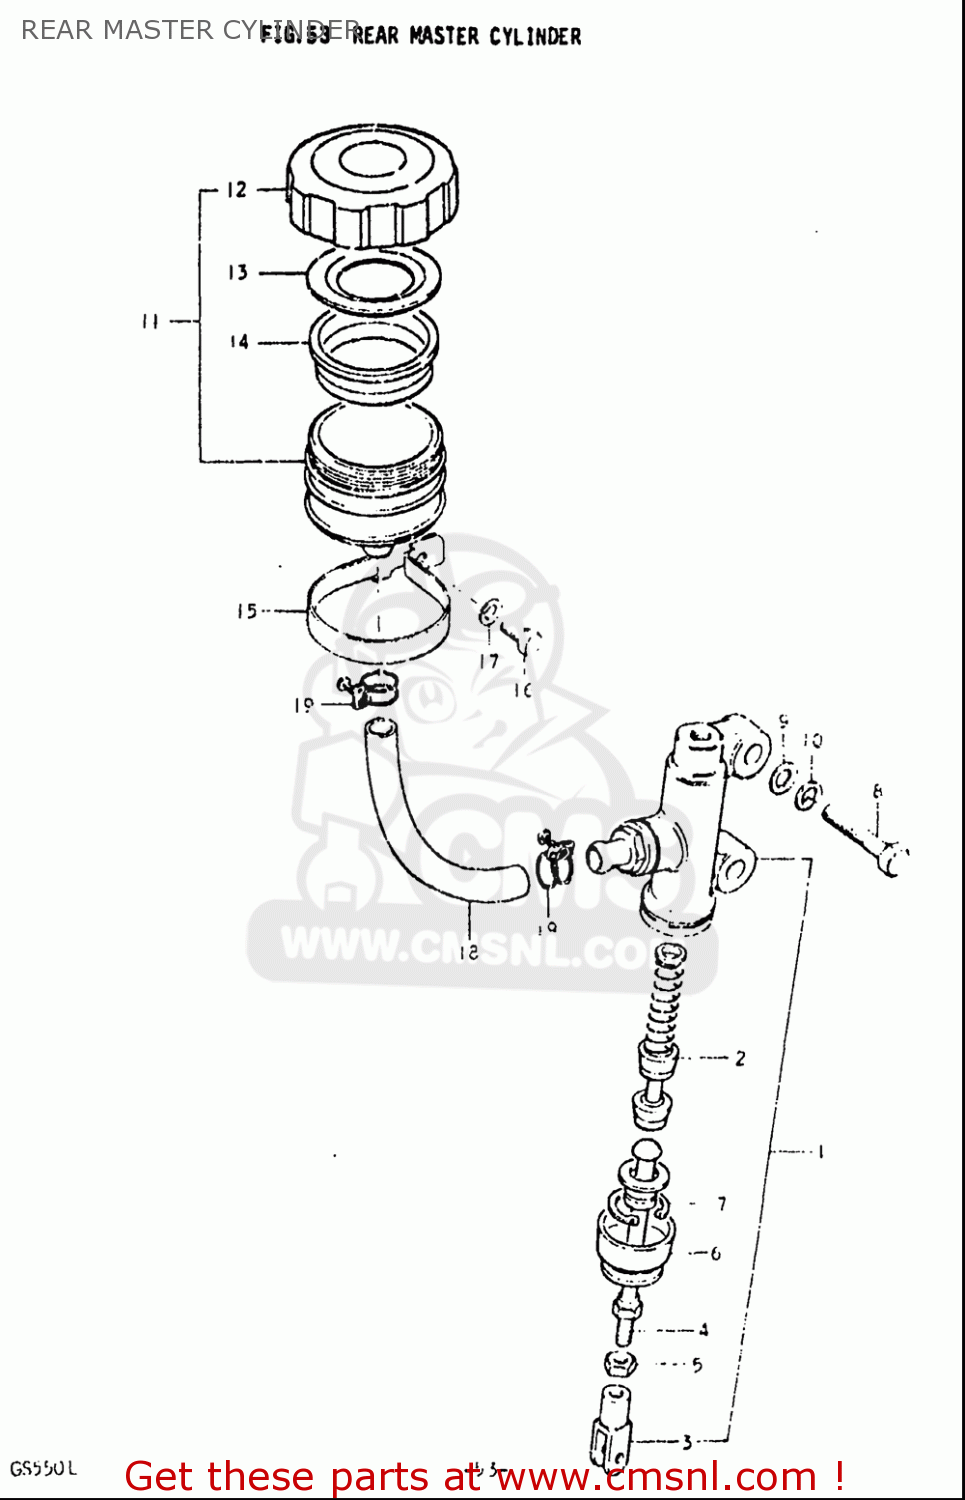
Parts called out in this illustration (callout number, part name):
1	CYLINDER ASSY,RR MASTER
2	PISTON/CUP SET
3	YOKE
4	ROD,PUSH
5	NUT
6	BOOT
7	CIRCLIP
8	BOLT
9	WASHER,LOCK
10	WASHER
11	TANK ASSY,RESERVOIR
12	CAP
13	PLATE,DIAPHRAGM
14	DIAPHRAGM
15	CLAMP
16	BOLT
17	WASHER,LOCK
18	HOSE,BRAKE RESERVOIR
19	CLAMP
